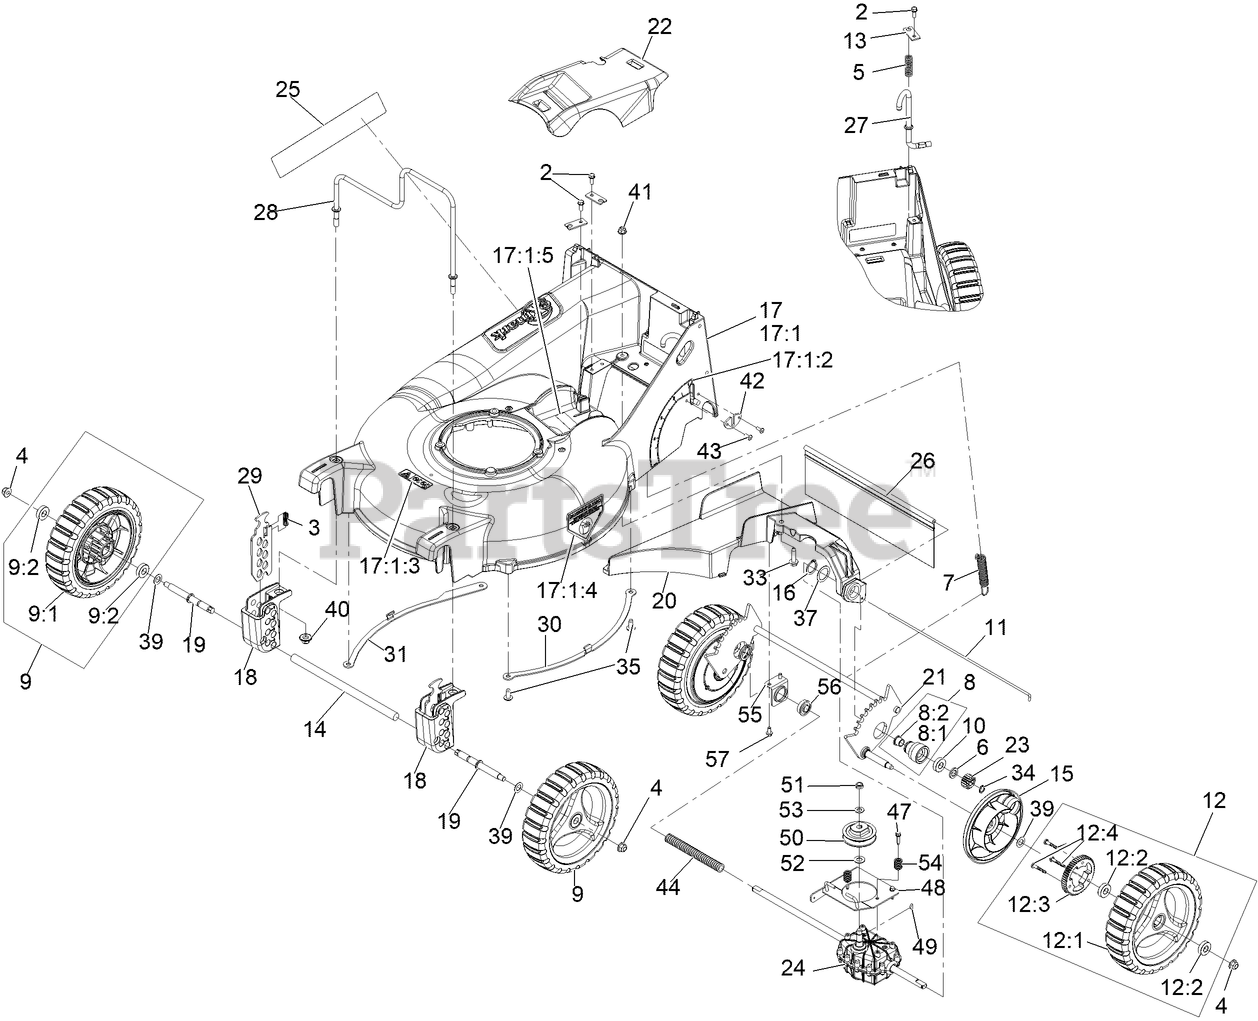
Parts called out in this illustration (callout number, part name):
2	SCREW-HWH
3	SPRING-COMPRESSION
4	NUT-HF, NI
5	SPRING-COMPRESSION
6	SPACER-BUSHING
7	SPRING-EXTENSION
8	HOUSING ASM
8:1	HOUSING-BEARING
8:2	BEARING-FLANGE
9	WHEEL ASM, 9" W/BEARINGS
9:1	WHEEL ASM, 9
9:2	BEARING-BALL
10	BEARING-BALL
11	ROD,SHIELD
12	WHEEL ASM, 9 W/GEAR
12:1	WHEEL ASM, 9
12:2	BEARING-BALL
12:3	GEAR-WHEEL, 52T
12:4	STUD-DRIVE
13	BRACKET,MOUNT
14	ROD,BUMPER
15	COVER,GEAR
16	RING-RETAINING
17	ASM-DECK EC21
17:1:2	DECAL-HEIGHT OF CUT
17:1:3	DECAL-WARNING, BLADE
17:1:4	DECAL-DANGER
17:1:5	DECAL-DANGER
18	BLOCK,FRONT QUADRANT
19	AXLE-WHEEL
20	Bracket-Transmission And Chute
21	WLD,REAR AXLE P21
22	COVER,BELT
23	GEAR-PINION, 15T
24	TRANSMISSION-HD, 4.5/1
25	DECAL-COMM 21 X-SERIES
26	SHIELD-TRAILING P21
27	ROD-HEIGHT ADJ P21
28	GUARD,ENGINE
29	PLATE, FRONT HEIGHT
33	SCREW-HWHTF
34	RING-RETAINING
35	SCREW-BHTF
39	WASHER-PLAIN
40	Nut-Nyloc 3/8-16 Flg
41	NUT-HF, NI
42	PLATE,WEAR
43	RIVET-BLIND
44	COVER-SHAFT-DRIVE
47	SCREW-SPECIAL
48	TRANSMISSION PLATE ASM
49	KEY-WOODRUFF
51	NUT-HEX
52	WASHER-THRUST
53	WASHER-FLAT
54	SPRING,COMPRESSION
55	MOUNT-BEARING
56	BEARING-BALL
57	SCREW-HWH
